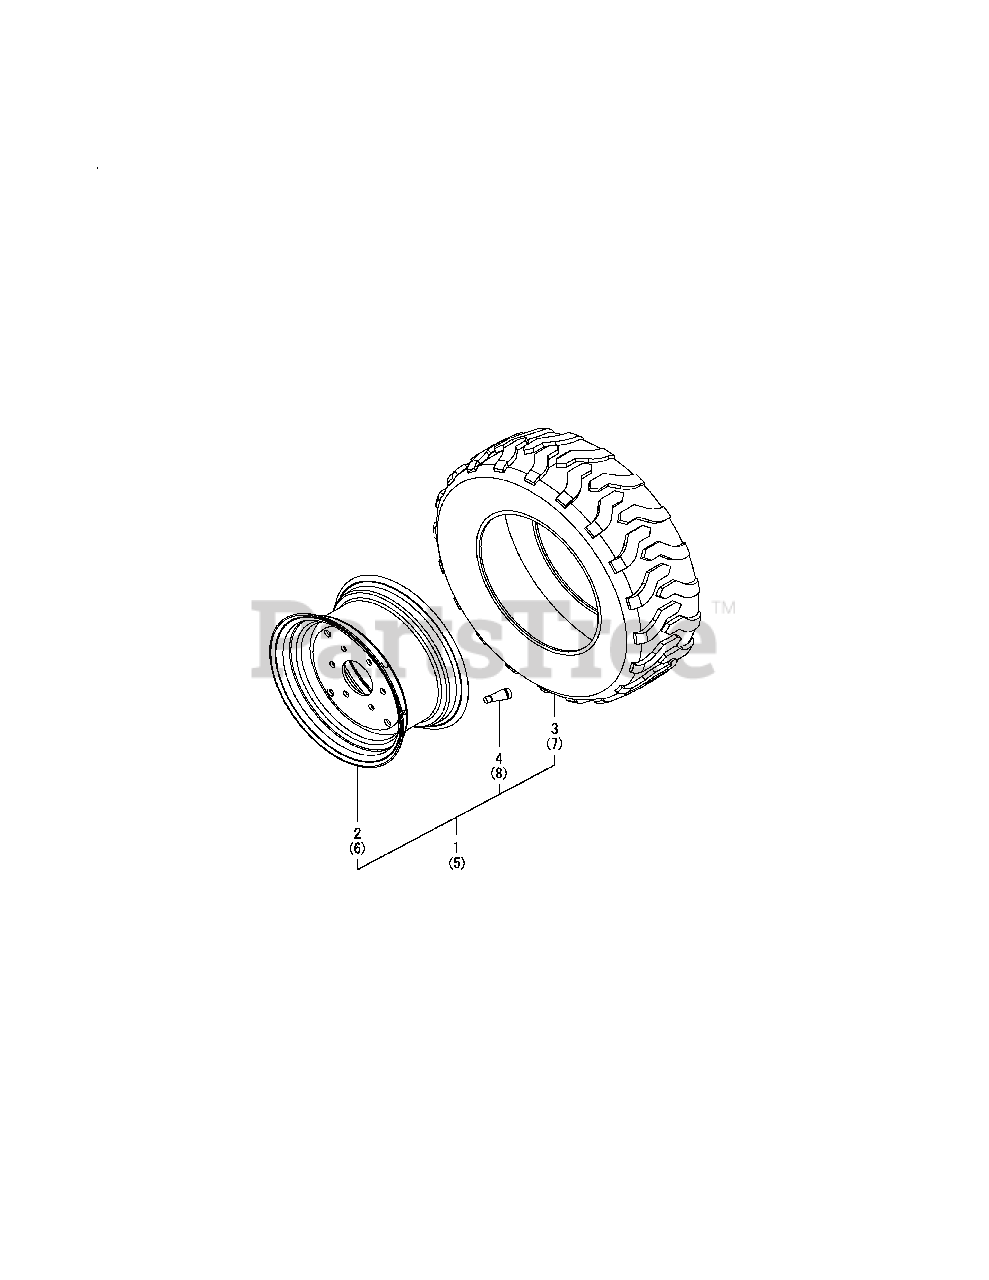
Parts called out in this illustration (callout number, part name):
1	TIRE ASM-FRNT IND LH
3	R4 TIRE-IND 25X8.50-14
5	TIRE ASM-FRNT IND RH
7	R4 TIRE-IND 25X8.50-14
